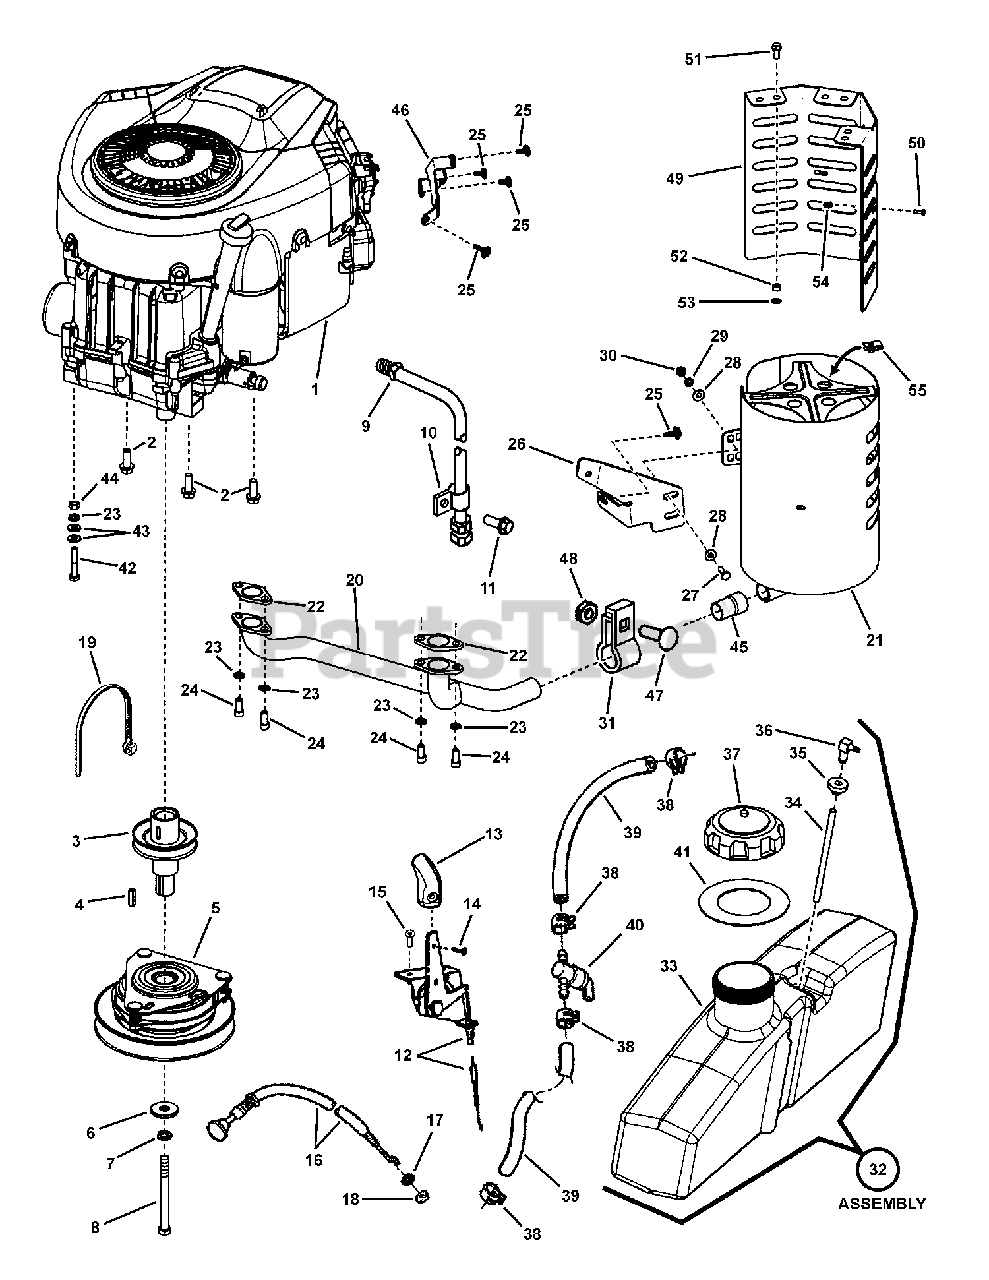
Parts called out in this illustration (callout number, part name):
1	* ENGINE, 20 HP Briggs Mod. 40G777-0184-E1 Extended Life Series V-Twin
1	* ENGINE, 22 HP Briggs Mod. 441777-0117-B1 Intek Twin
2	SCREW, 3/8-16 x 1" Hex Washer Self-Tap
3	ASSEMBLY, Engine Pulley
4	KEY, 1/4 Square x 1"
5	CLUTCH, Ogura JD-11
6	WASHER, .468 ID x 1.50 OD x .188 Flat
7	WASHER, 7/16" Split Lock
8	SCREW, 7/16-20 x 4-1/2" Hex Head Cap, GR 5
9	HOSE, Oil Drain
10	HARNESS CLIP, 5/8"
11	BOLT, 5/16-18 x 5/8" Hex Flange Lock, GR 5
12	CABLE, 48" Throttle Control
13	KNOB, Throttle, Red RZT
14	SCREW, #10-16 x 3/4" Pan Head Self-Tap
15	SCREW, 1/4-20 x 5/8" Pan Head Self-Tap (Torx)
16	CABLE, 54" Choke Control
17	WASHER, 3/8" Internal Tooth Lock
18	NUT, 3/8-24 Hex, GR B
19	CABLE TIE, 7"
20	MANIFOLD, B&S V-Twin Intek
21	** MUFFLER, LC YZ
21	MUFFLER, RZT
22	GASKET, Exhaust, 20 HP Intek
23	WASHER, 5/16" Split Lock
24	SET SCREW, 5/16-18 x 3/4" Socket Head, GR 8
25	SCREW, 1/4-20 x 3/4" Hex Head Flange, GR 5, YZ
26	BRACKET, Muffler 20/22HP Briggs
27	SCREW, 1/4-20 x 1" Hex Head Cap, GR 5
28	WASHER, .28 x .63 x .06 Flat, GR 5
29	WASHER, 1/4" Split Lock
30	NUT, 1/4-20 Hex, GR 5 or B
31	CLAMP, Muffler
32	ASSEMBLY, Fuel Tank, RZT
33	FUEL TANK
34	DIP TUBE
35	GROMMET
36	ELBOW, 90 Degree
37	CAP, Fuel, 3-1/2"
38	CLAMP, Fuel Line
39	HOSE, Fuel, .25 I.D. x 14" long
39	HOSE, Fuel, .25 I.D. x 5" long
40	VALVE, Fuel
41	SEAL, Tank
42	SCREW, 5/16-18 x 1-3/4" Hex Head Cap, GR 5, YZ
43	WASHER, .34 x .69 x .08 Flat
44	NUT, 5/16-18 Hex, GR 5 or B
45	TUBE, Manifold Extension
46	BRACKET, Fuel Pump
47	BOLT, 5/16-18 x 1-1/4" Square Neck Carriage, GR 5
48	NUT, 5/16-18 Hex Flange Lock
49	HEAT SHIELD, Muffler, ERZT, MY06
50	SCREW, #8-32 x 1/2" Cross Recess Pan Head
51	SCREW, 1/4-20 x 5/8" Hex Flange Lock
52	BUSHING, .250 ID x .375 OD x .25 Long
53	RETAINER, 1/4" Bolt
54	PUSH NUT
55	SPEED NUT, 1/4-20 U Type/070/.140 Black
